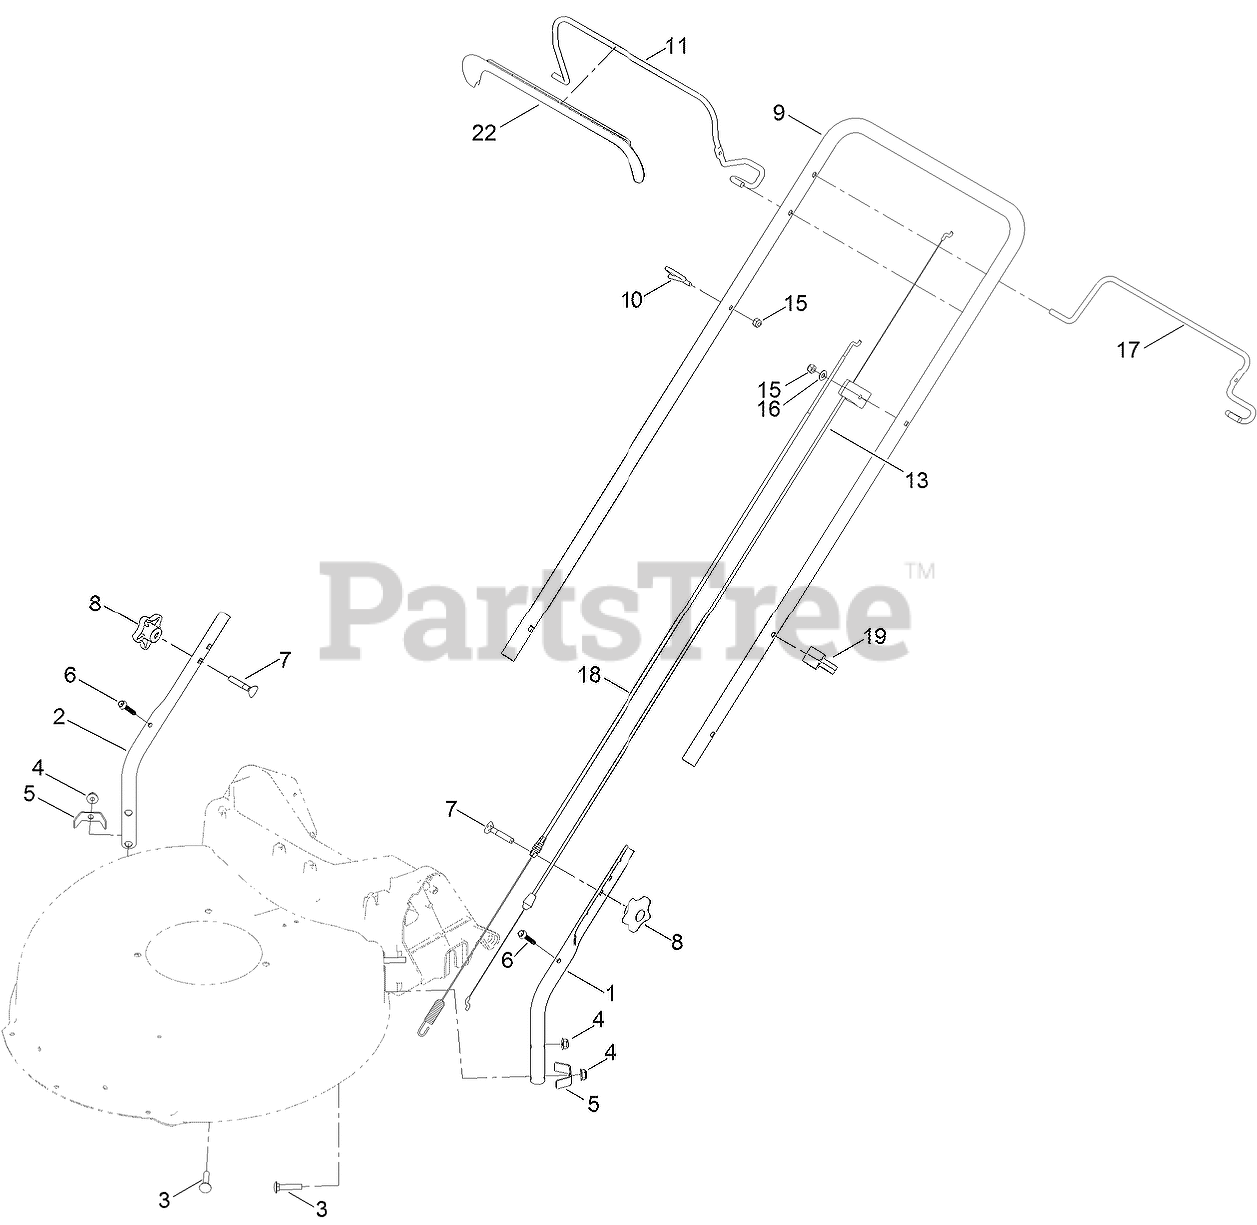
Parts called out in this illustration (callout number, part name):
1	HANDLE-LOWER, LH
2	HANDLE-LOWER, RH
3	BOLT-CARR
4	NUT-FLANGE, NI
5	BRACKET-CHUTE
6	SCREW-FLANGE, SERRATED
7	SCREW-HANDLE
8	KNOB-HANDLE
9	HANDLE-UPPER
10	GUIDE-ROPE
11	BAIL-BRAKE
13	CABLE-BRAKE
15	NUT-LOCK, NI
16	WASHER-FLAT
17	BAIL-TRACTION
18	CABLE-TRACTION
19	GUIDE-CABLE
22	COVER-BAIL
